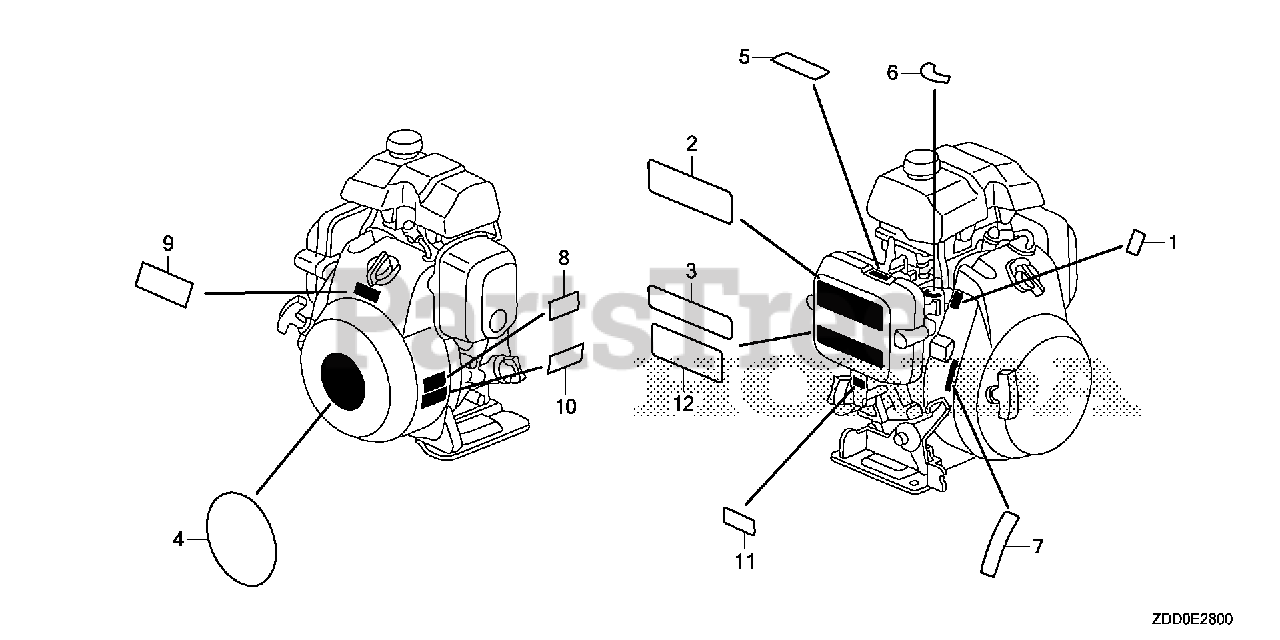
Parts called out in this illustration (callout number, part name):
2	MARK, OPERATOR CAUTION (ENGLISH)
4	EMBLEM (GX100) (RAMMER)
5	MARK, CHOKE INDICATION
9	MARK, EX. CAUTION (ENGLISH)
11	MARK, TYPE (KRB8)
